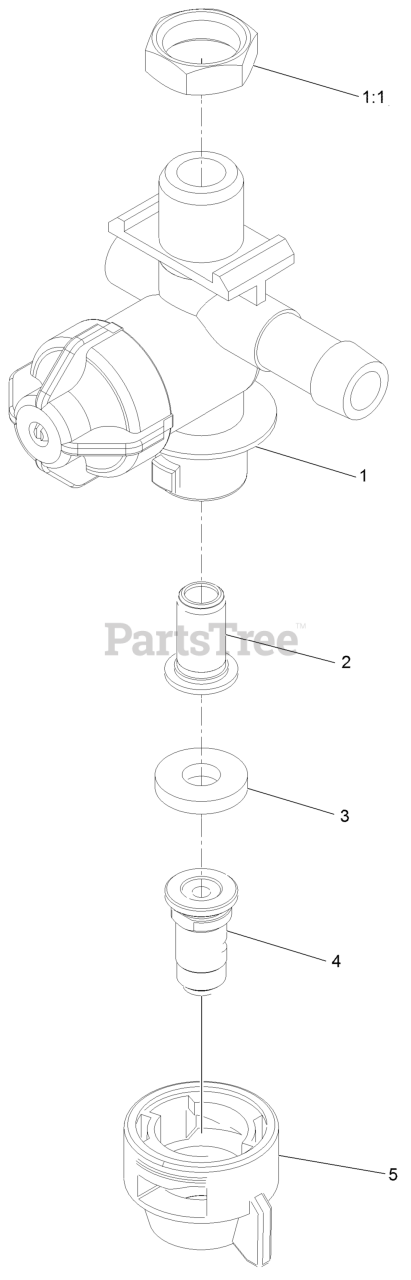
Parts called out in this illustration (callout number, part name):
1	LH NOZZLE BODY ASM
1:1	NUT-NYLON
2	STRAINER-TIP
4	NOZZLE-SPRAY, WHITE
5	CAP-NOZZLE
